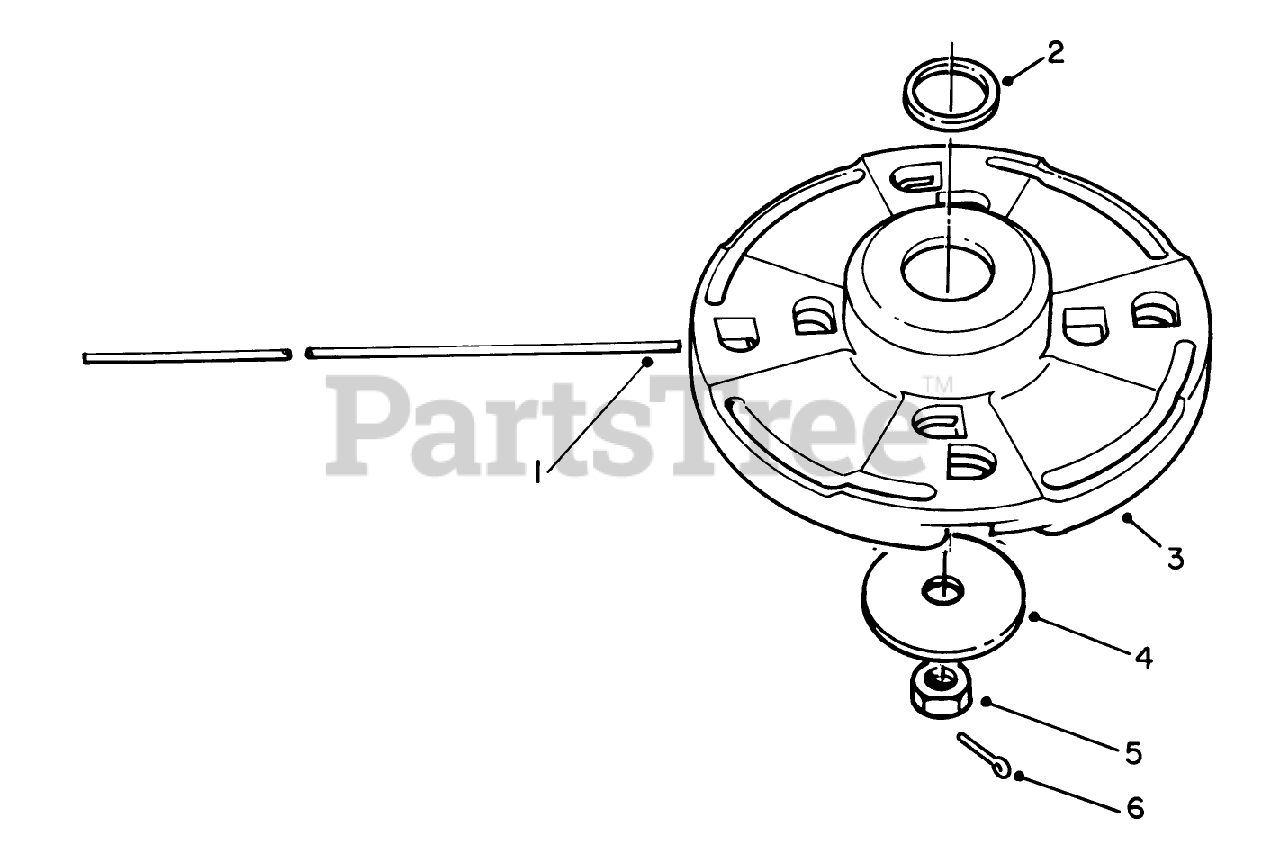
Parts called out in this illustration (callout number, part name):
1	Line-Cutting
2	SPACER
4	WASHER
6	1/16 X 1 LG COTTER PIN
